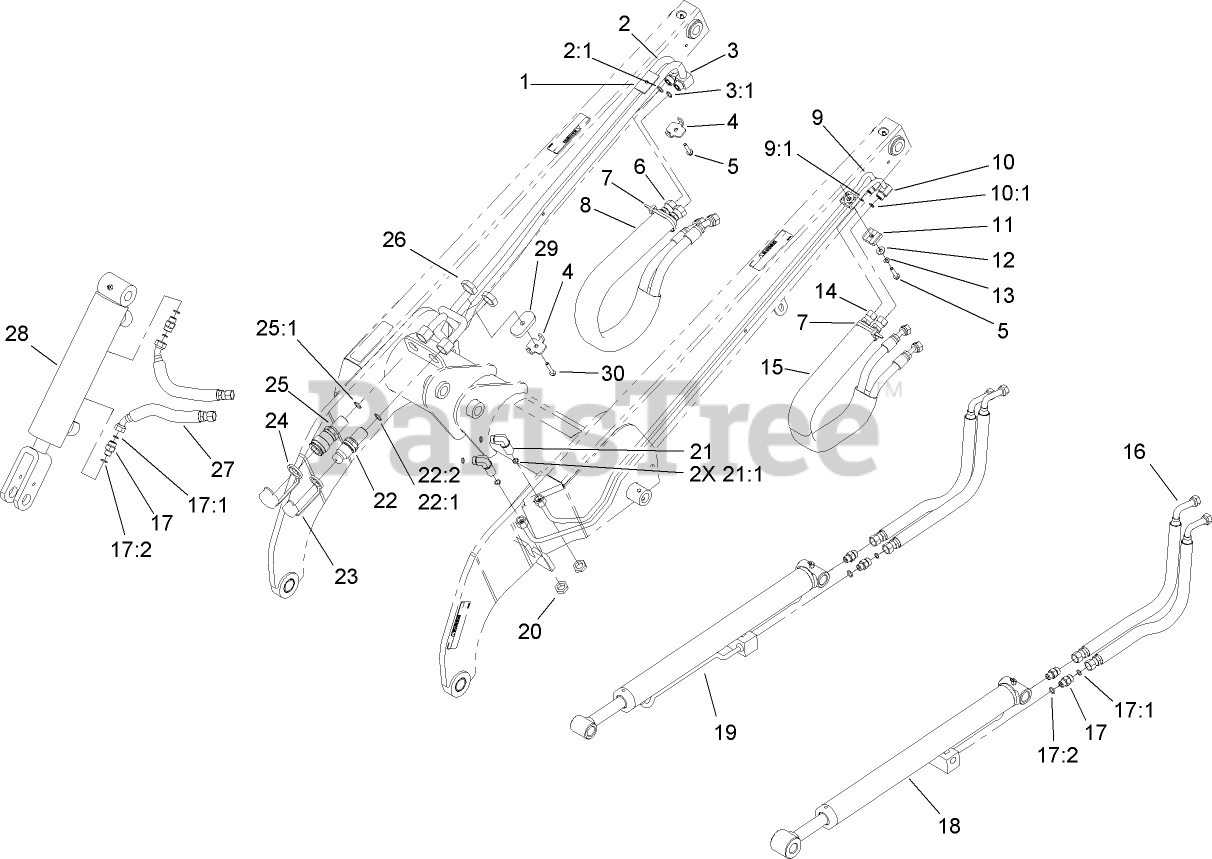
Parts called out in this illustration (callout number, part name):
1	SPACER-HARDLINE
2	HYD TUBE ASM
2:1	O-RING
3	HYD TUBE ASM
3:1	O-RING
4	PLATE-CLAMP, TUBE
5	SCREW-HWH
6	HOSE-HYD
7	TIE-CABLE
8	SLEEVE-PROTECTIVE
9	HYD TUBE ASM
9:1	O-RING
10	HYD TUBE ASM
10:1	O-RING
11	CLAMP-TUBE
12	WASHER-FLAT
13	WASHER-LOCK
14	HOSE-HYD
15	SLEEVE-PROTECTIVE
16	HOSE-HYD
17	FITTING-STRAIGHT
17:1	O-RING
17:2	O-RING
18	LH LIFT CYLINDER ASM
19	RH LIFT CYLINDER ASM
20	NUT-LOCK
21	UNION-BULKHEAD
21:1	O-RING
22	BULKHEAD NIPPLE ASM
22:1	O-RING
23	CAP-DUST, NIPPLE
24	CAP-DUST, COUPLER
25	BULKHEAD COUPLER ASM
25:1	O-RING
26	NUT-LOCK, BULKHEAD
27	HOSE-HYD
28	TILT CYLINDER ASM
29	PLATE-HARDLINE
30	SCREW-HWH
